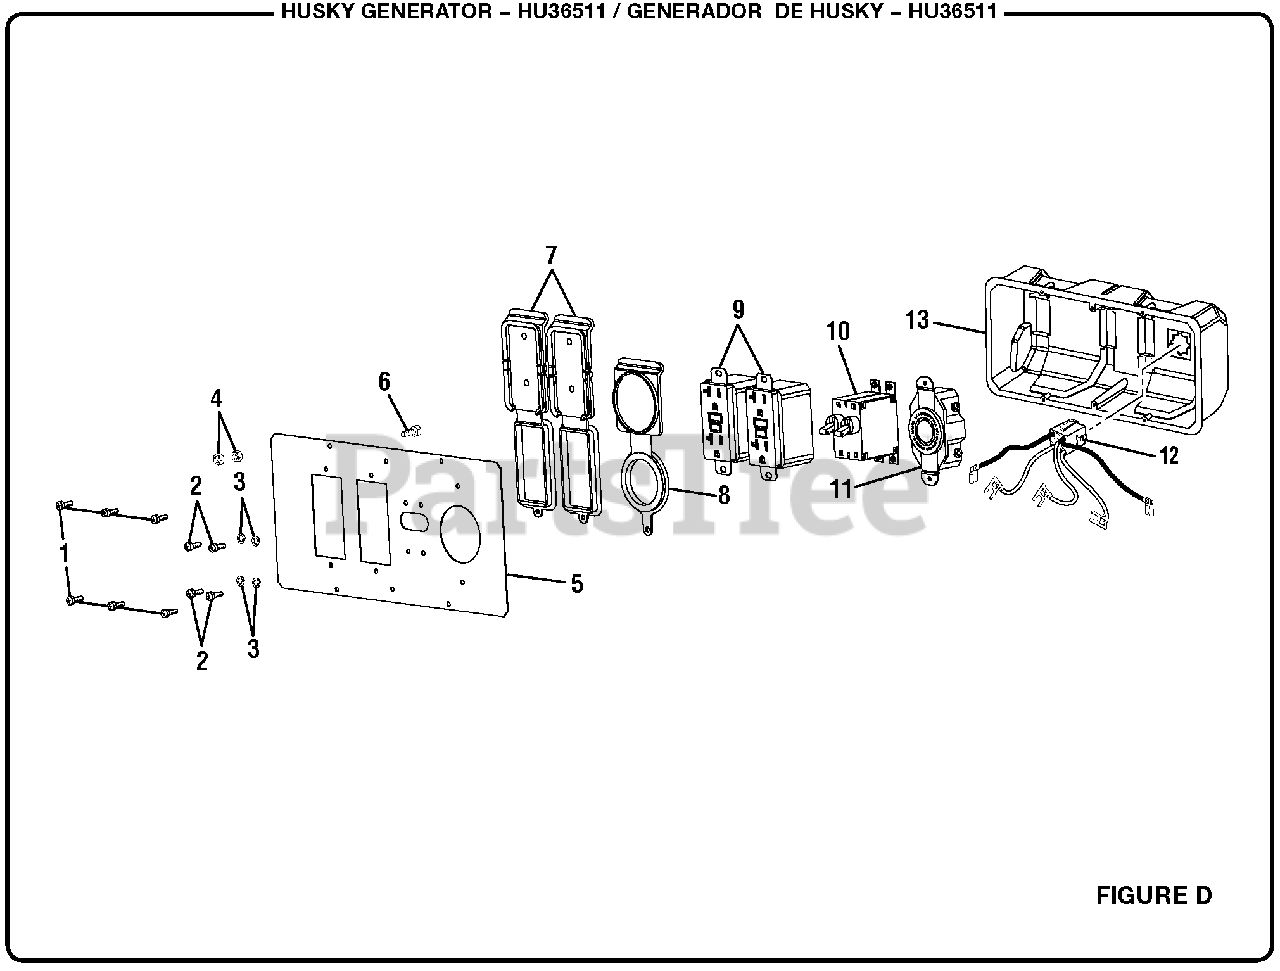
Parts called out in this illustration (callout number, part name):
1	Screw (6-20 x 3/8 in)
2	Screw (M3 x 6)
3	Lock Washer
4	Hex Nut (1/4-20)
5	Cover Plate
6	Screw (1/4-20 x 5/8 in, Hex Hd)
7	Outlet Cover (120 Volt)
8	Outlet Cover (240 Volt)
9	Duplex Receptacle (120 Volt, GFCI)
10	Circuit Breaker (15 Amp, 125 Volt, HU36511)
11	Twist Lock Receptacle (120/240 Volt, 20 Amp)
12	Connector w/Leads
13	Rear Control Panel
